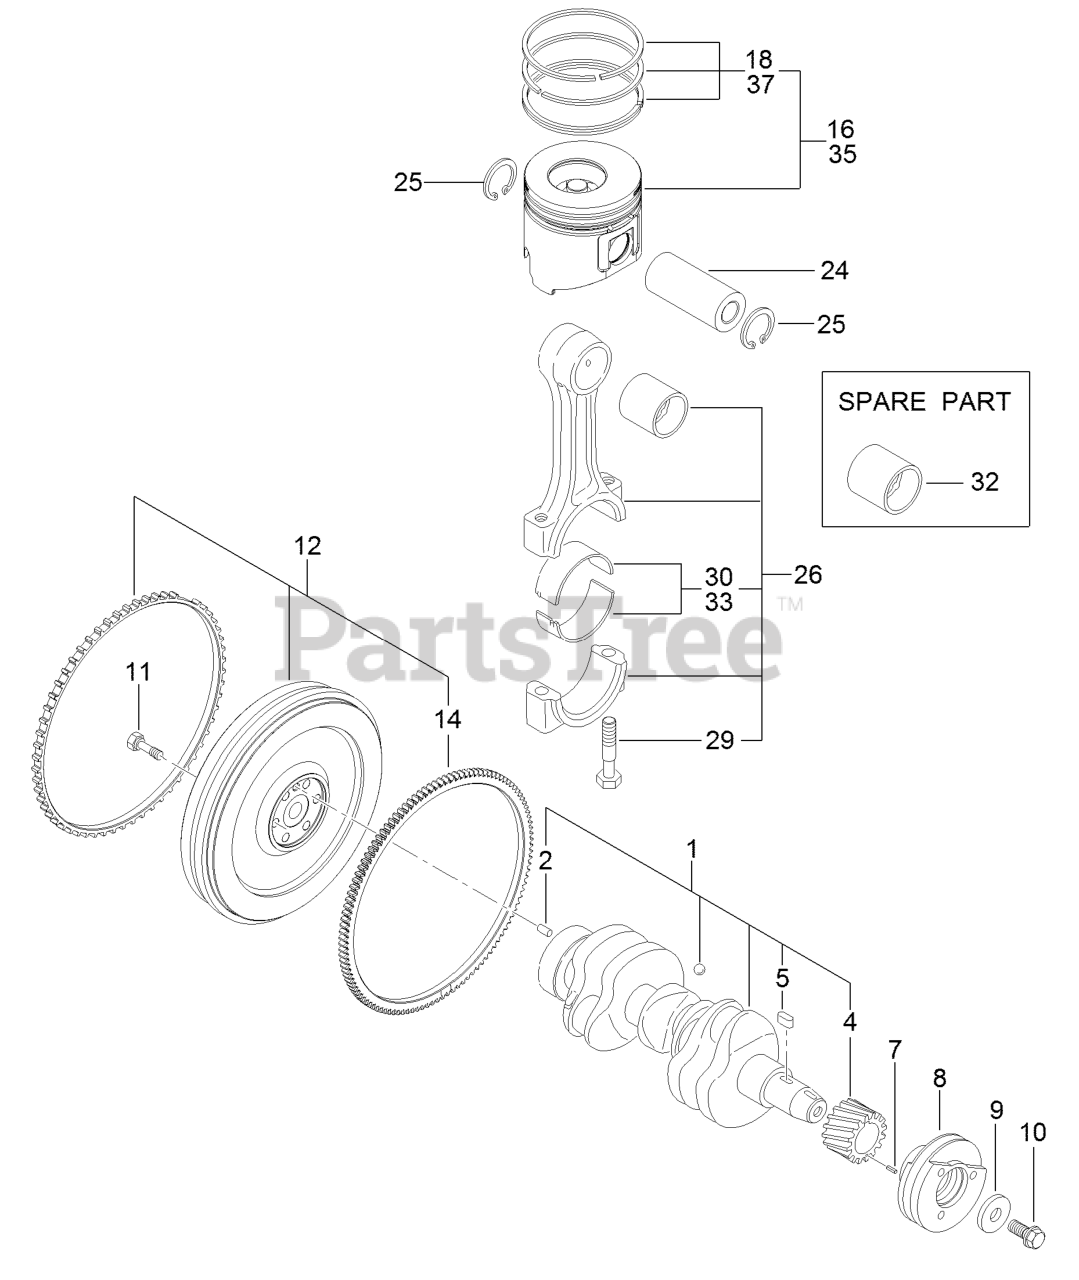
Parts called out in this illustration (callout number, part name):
1	Crankshaft ASM
7	Pin-Spring
8	Pulley-V
12	Flywheel ASM
16	Piston ASM
18	Piston Ring ASM
26	Connecting Rod ASM
30	Pin-Crank
32	Pin-Piston
33	Pin-Crank (.25)
35	Piston ASM (0.25 O S)
37	Ring Set (0.25 O S)
